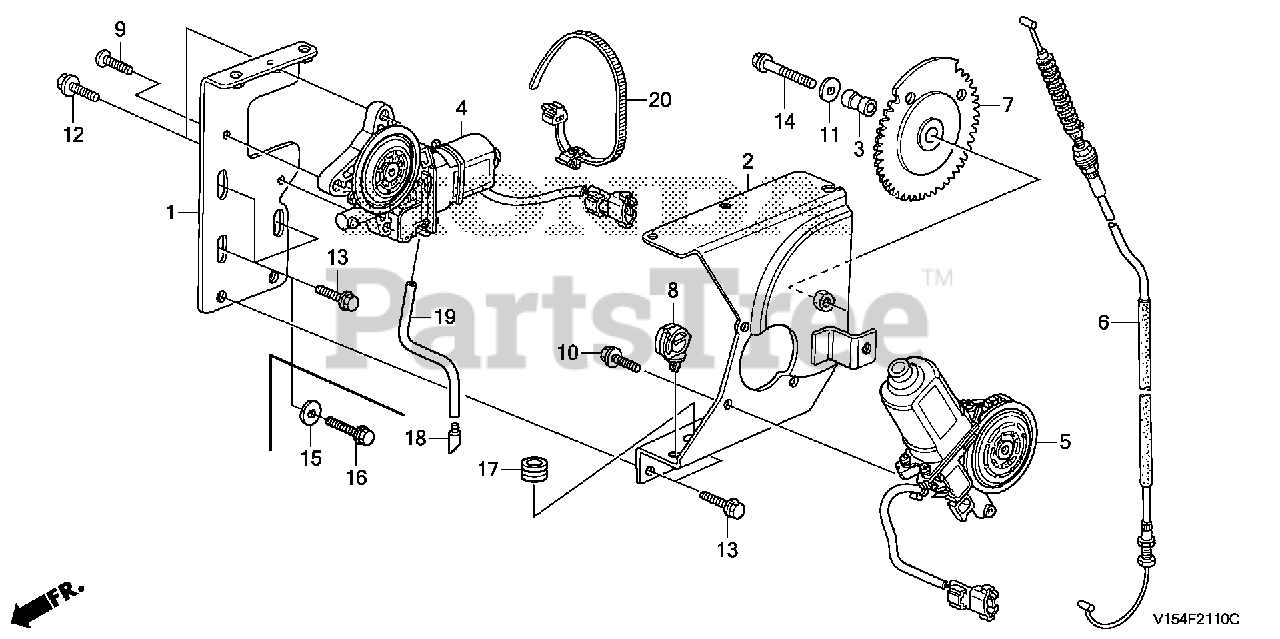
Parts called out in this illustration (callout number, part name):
1	BRACKET, CHUTE MOTOR
2	BRACKET, CHUTE GUIDE MOTOR
3	COLLAR, CLUTCH GUIDE GEAR
4	MOTOR ASSY., CHUTE
5	MOTOR ASSY., CHUTE GUIDE
6	CABLE, CHUTE GUIDE
7	GEAR, CHUTE GUIDE MOTOR
8	CLIP, WIRE HARNESS (25MM)
9	SCREW, PAN (6X12)
10	SCREW, TAPPING (5X14)
11	WASHER, PLAIN (6MM)
12	BOLT, FLANGE (6X12)
13	BOLT, FLANGE (6X12)
14	BOLT, FLANGE (6X30)
15	WASHER, PLAIN (6MM)
16	BOLT, FLANGE (6X16)
17	RUBBER, TURN SIGNAL BOLT MOUNTING (NOT AVAILABLE)
18	BELL, MOUTH
19	BULK HOSE, VACUUM (3.5X1000) (3.5X75)
20	BAND, WIRE HARNESS
